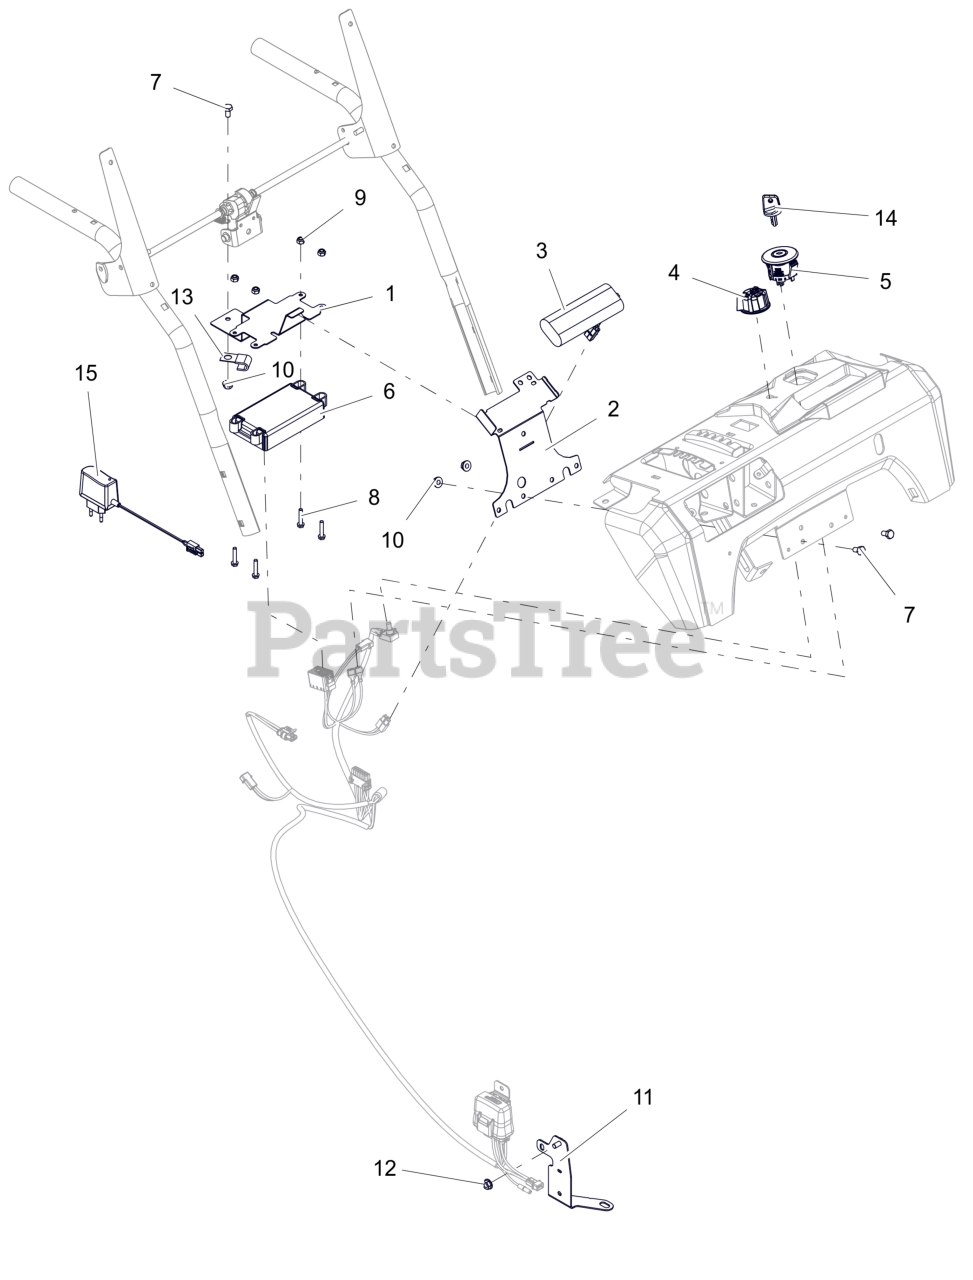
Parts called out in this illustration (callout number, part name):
1	BRACKET, ENGINE EFI-LCT LOWER
2	BRACKET, ENGINE EFI-LCT UPPER
3	BATTERY, SNOW EFI - 7.2V
4	KNOB- CONTROL EFI
5	IGNITION SWITCH ASM - 2 POS
6	ECU SERVICE LCT/CSI - 369CC
7	BLT,HEX .25-20X.50 G5 ZCC
8	BLT, HWH #10-24X1.00 ZCC
9	NUT-LK-NYL #10-24 G2 ZCC
10	NUT-LK-TOP-FLG .250-20 GF ZCC
11	WLDMT- LG BLOCK FUSE MOUNT
12	NUT-LK-CTR-FLG .25-20 ZC120
13	J-CLAMP
14	KEY- IGNITION
15	CHARGER, BATTERY-EFI 7.2V (EU)
